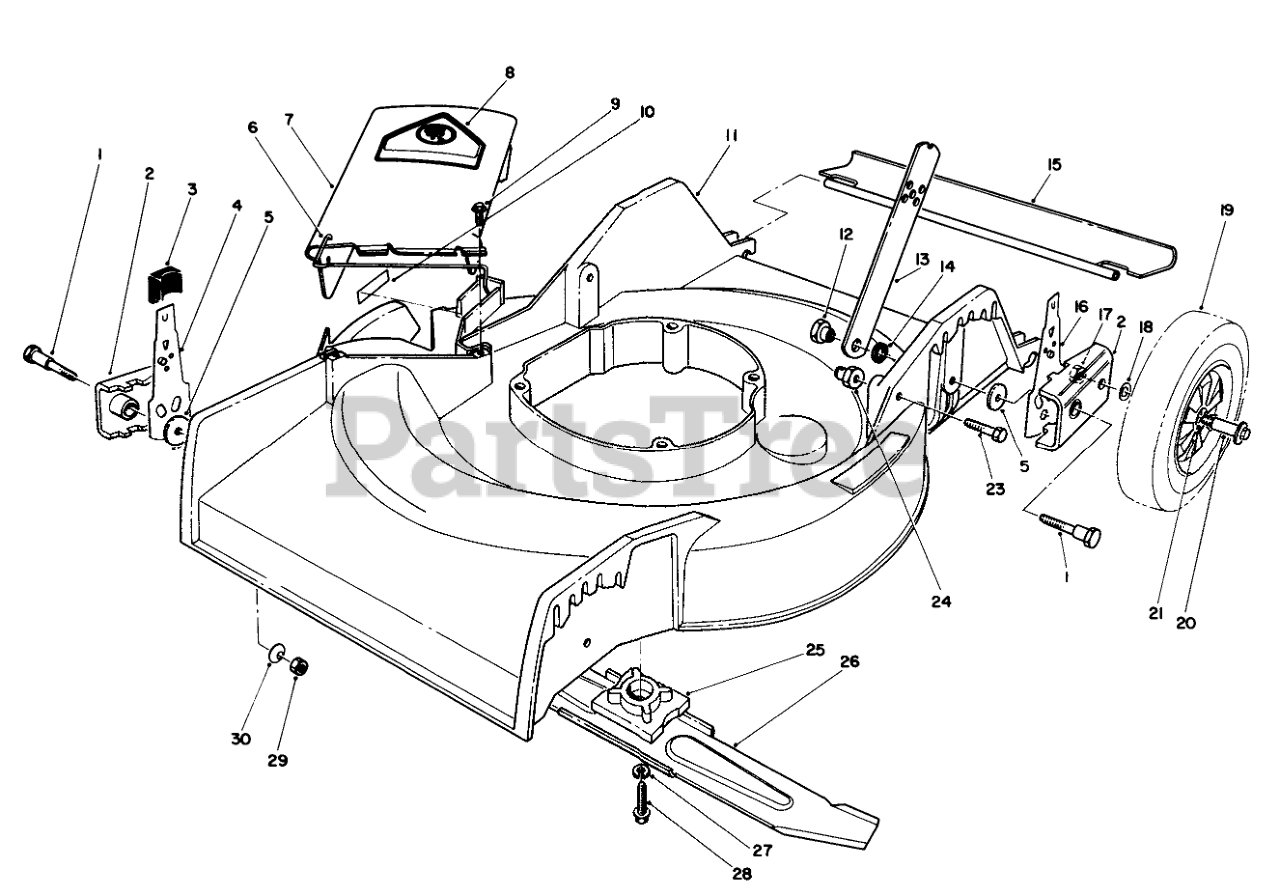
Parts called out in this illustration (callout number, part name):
1	PIVOT SCREW
2	HP PIVOT ARM ASM
3	KNOB-ARM
4	SPRING ARM ASSEMBLY
5	PIVOT WASHER
6	SPRING HINGE
7	Deflector Assembly (Incl. Ref. #6 & 8)
8	DECAL-DANGER
9	SCREW-HWH
10	DANGER DECAL
11	Housing (Incl. Ref. #10)
12	HANDLE PIVOT NUT
13	HANDLE LATCH
14	SPACER
15	SHIELD - TRAILING
16	SPRING ARM ASSEMBLY
17	Nut
18	WASHER
19	Wheel & Tire Assembly (Incl. Ref. #21)
20	BOLT-WHEEL
21	BUSHING
23	SCREW-HH
24	HANDLE PIVOT NUT
25	BLADE RETAINER
26	Blade
27	WASHER-LOCK
28	SCREW-HH
29	NUT-LOCK, NI
30	WASHER-BELLEVILLE
